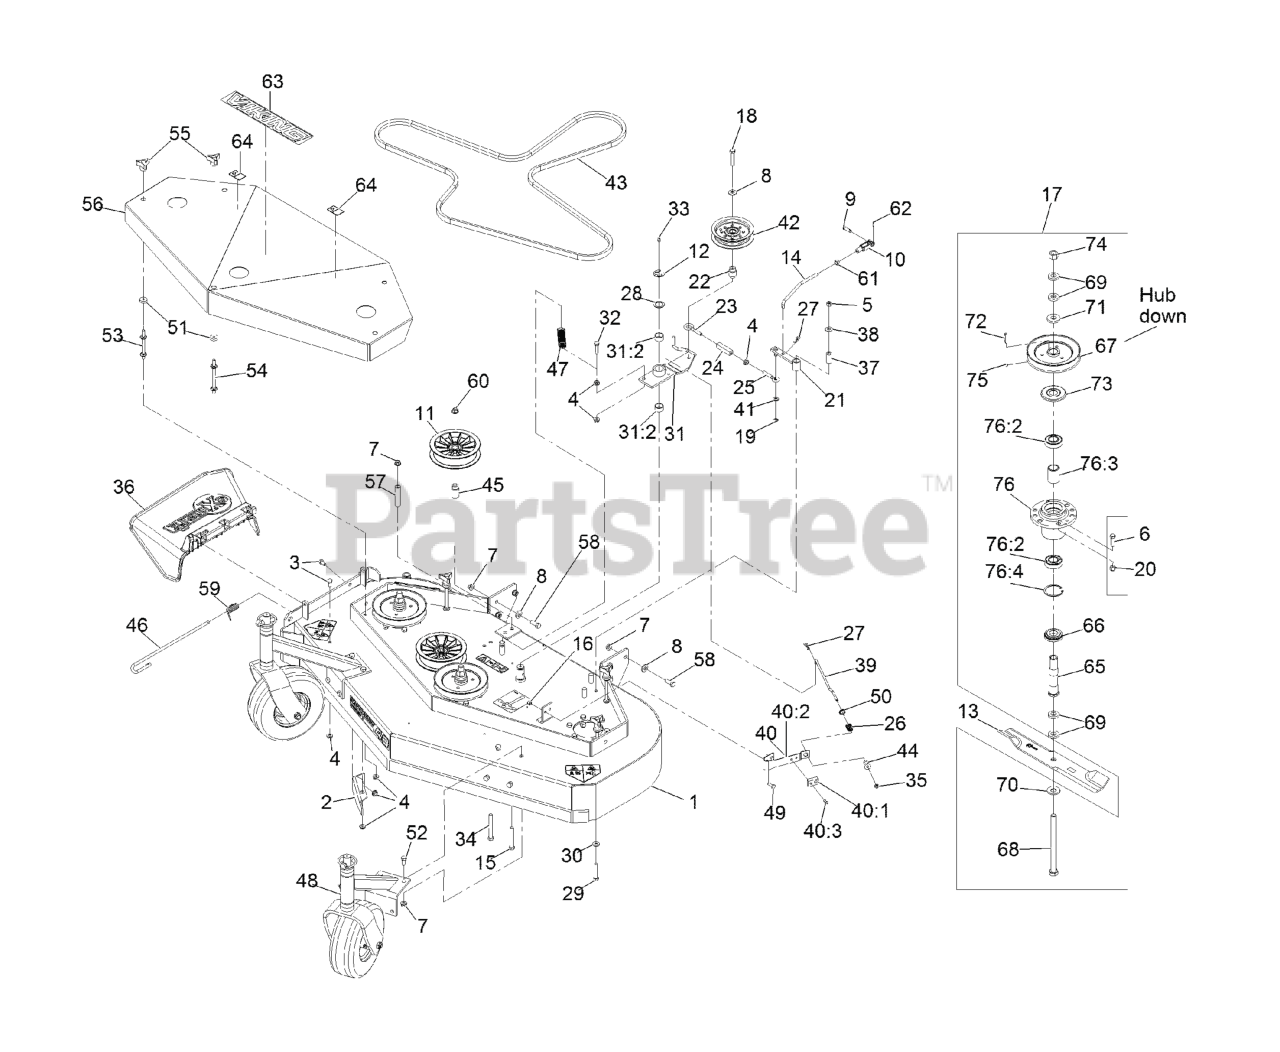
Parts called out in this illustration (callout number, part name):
1	DECK-SERVICE, 48
2	BAFFLE-DOGLEG
3	SCREW-HH
5	NUT-LOCK, NI
6	SCREW-HH
7	NUT-HHF, WHIZ
8	WASHER-BELLEVILLE
9	PIN-CLEVIS
10	YOKE-ADJUSTABLE
11	PULLEY,IDLER 5"
12	RING-RETAINING, EXT
14	ARM-LINKAGE, ASSIST
15	SCREW-HH
16	NUT-LOCK, NI
17	ASM, CUTTER HOUSING OUTER
18	SCREW-HH
19	RING-RETAINING, EXT
20	NUT-LOCK, NI
21	ARM-ASSIST, 32/36
22	BUSHING-ENGAGEMENT
23	EYEBOLT-THREAD, LH
24	BODY-TURNBUCKLE
25	EYEBOLT-THREAD, RH
26	SPRING-COMPRESSION
27	PIN-COTTER
28	WASHER-SPINDLE
29	SCREW-HH
30	WASHER-SPRING
31	IDLER ARM ASM
31:2	SLEEVE-BEARING
32	SCREW-HH, SPECIAL
33	FITTING-GREASE
34	SCREW-HH
35	NUT-LOCK, NI
36	CHUTE DEFLECTOR XRK M056
37	TUBE-PIVOT
38	WASHER-FLAT
39	ROD-BRAKE
40	PAD AND SPRING ASM
41	WASHER-PLAIN
43	BELT,BLADE 48
44	SPACER-FLANGED
45	BUSHING-IDLER
46	PIN-CHUTE
47	SPRING-EXTENSION
48	ASM-CASTER MNT W/WEIGHT
49	SCREW-HH
50	RING-PUSH ON
52	SCREW-HH
53	STUD-SHIELD, BELT (SHORT)
54	STUD-SHIELD, BELT (LONG)
55	KNOB-3 PRONG
56	Shield Weldmt, 48"
56	ASM,SHIELD W/DECALS 48 VI
58	SCREW-HH
59	SPRING, TORSION
60	NUT-HF, NI
61	NUT-HEX
62	PIN-COTTER
63	DECAL, VIKING HYDRO MODEL
64	DECAL-WARNING
65	TUBE-SPINDLE, SHORT
66	SPACER-GUARD, BOTTOM
67	SHEAVE
68	SCREW-CAP, HH
70	WASHER-SPRING
71	WASHER-RETAINER, SHEAVE
73	GUARD-BEARING, TOP
74	NUT-HEX
75	SETSCREW
76	Cutter Housing ASM
76	KIT, CUTTER HOUSING
76:2	BEARING-JACKSHAFT
76:3	SPACER-BEARING
76:4	RING-SNAP
